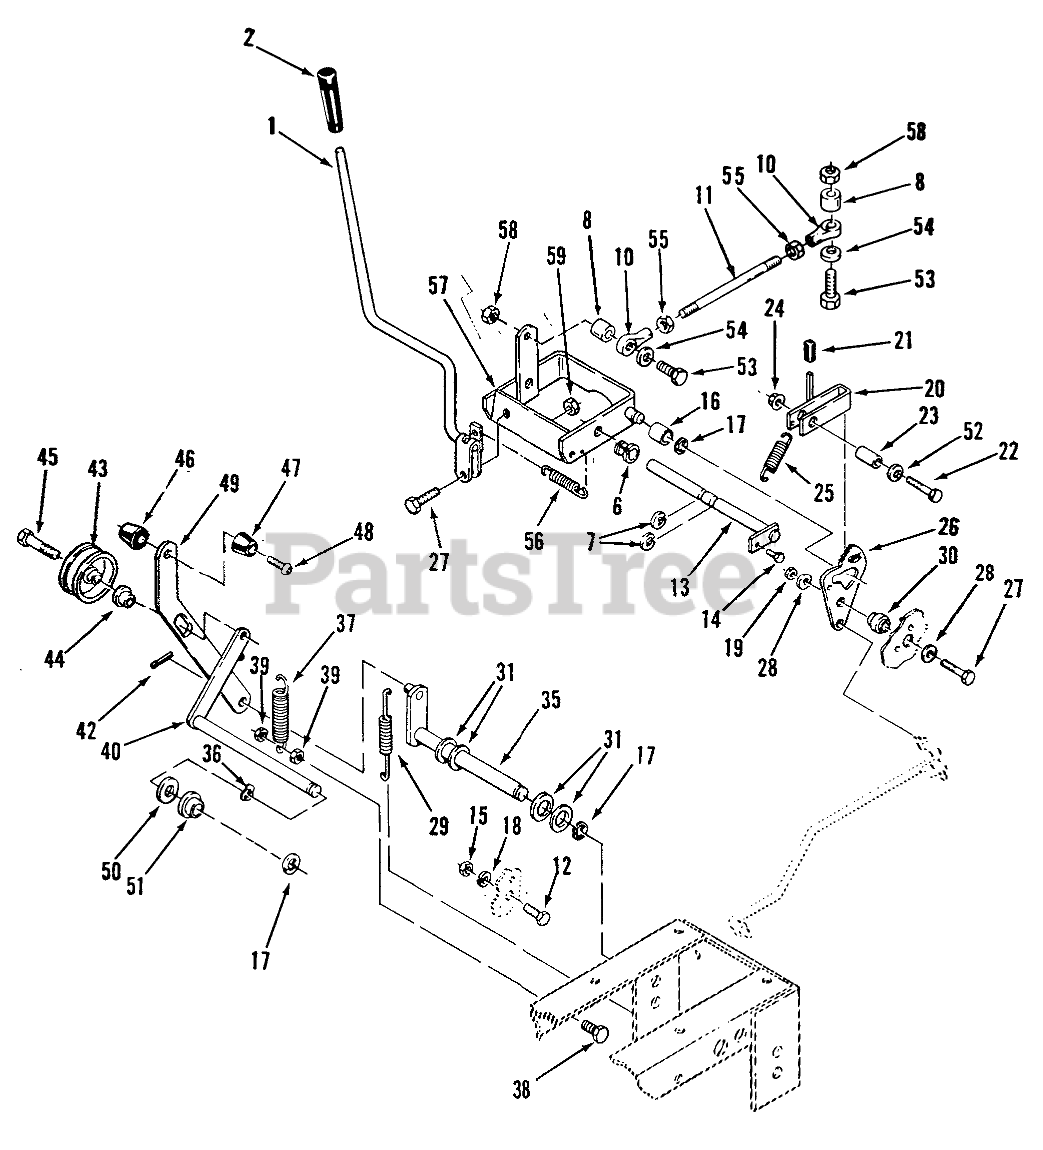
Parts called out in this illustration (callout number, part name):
1	ASS'Y-ARM CONTROL B
6	NYLINER BUSHING
7	E Ring
8	Spacer
10	ASSY ROD END
11	ROD-CONTROL
12	Bolt
13	ASSY-ROD CAM PIVOT
14	SCREW
15	Nut
16	BEARING-CAM RETURN
17	E Ring
18	LOCKWASHER
19	NUT
20	PAWL HDL ASSY B
21	VALVE LEVER GRIP
22	Bolt
23	SPACER
24	LOCKNUT-FLANGE
25	Spring
26	Cam Plate
27	BOLT
28	Washer
29	SPRING-EXTENSION
30	Spacer
31	Washer
35	ASSY-BRAKE LEVER
36	WASHER-WAVE
37	SPRING-EXTENSION
38	Bolt
39	Nut
40	ASSY-ARM/ROD WA
42	Cotter Pin
43	PULLEY-IDLER
44	SPACER-BRAKE LINK
45	BOLT-SPECIAL HEX
46	KNOB
47	KNOB
48	BOLT-4
49	Handle
50	Washer
51	BUSHING-FLANGED
52	Washer
53	Bolt 1/4-20 X 1 1/2
55	Jam Nut 1/4-28
56	SPRING
57	Cam Comtrol
58	NUT
